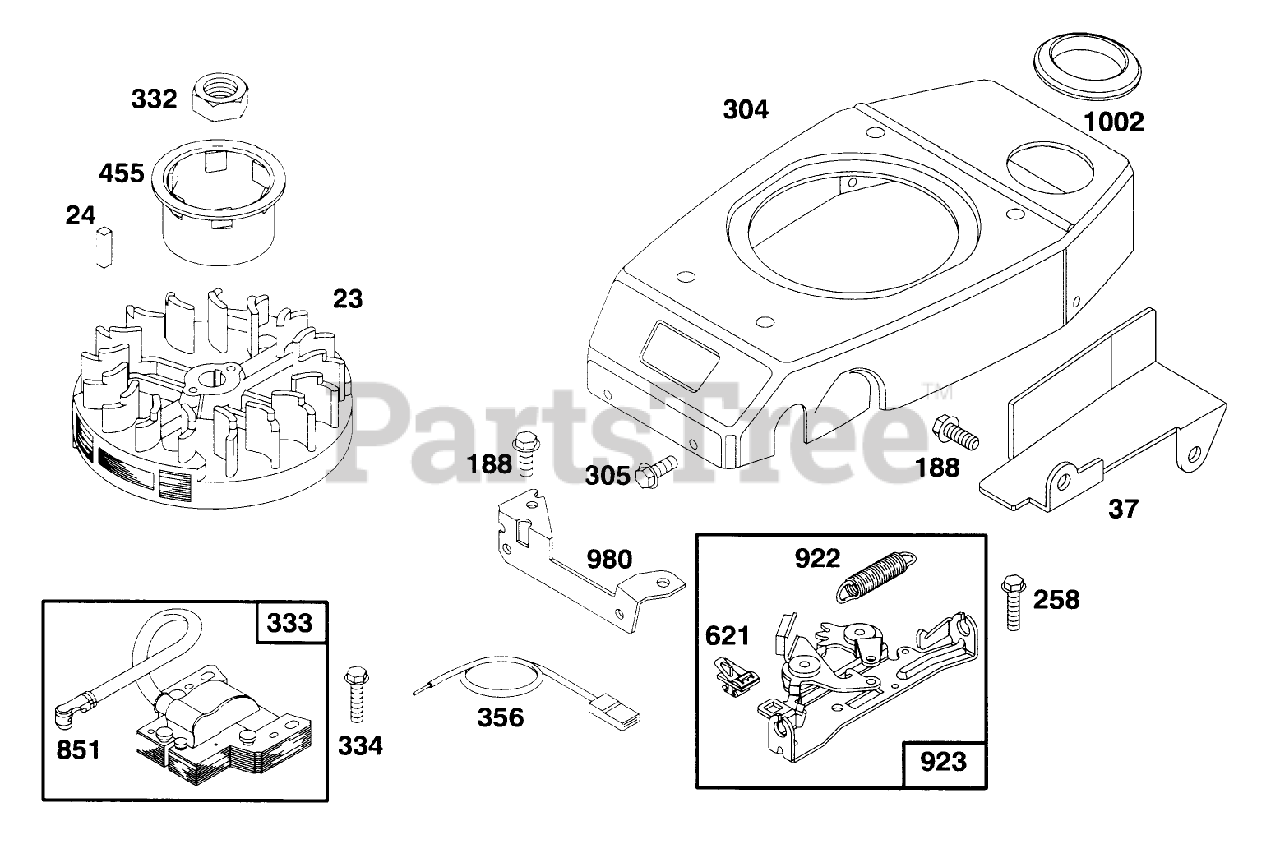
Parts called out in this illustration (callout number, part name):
24	KEY - FLYWHEEL
37	GUARD - FLYWHEEL
304	HOUSING - BLOWER
305	SCREW - HEX HEAD
332	NUT - HEXAGON
334	SCREW - SEM
356	WIRE - GROUND
621	STOP SWITCH
980	BRACKET-BLOWER HSG
